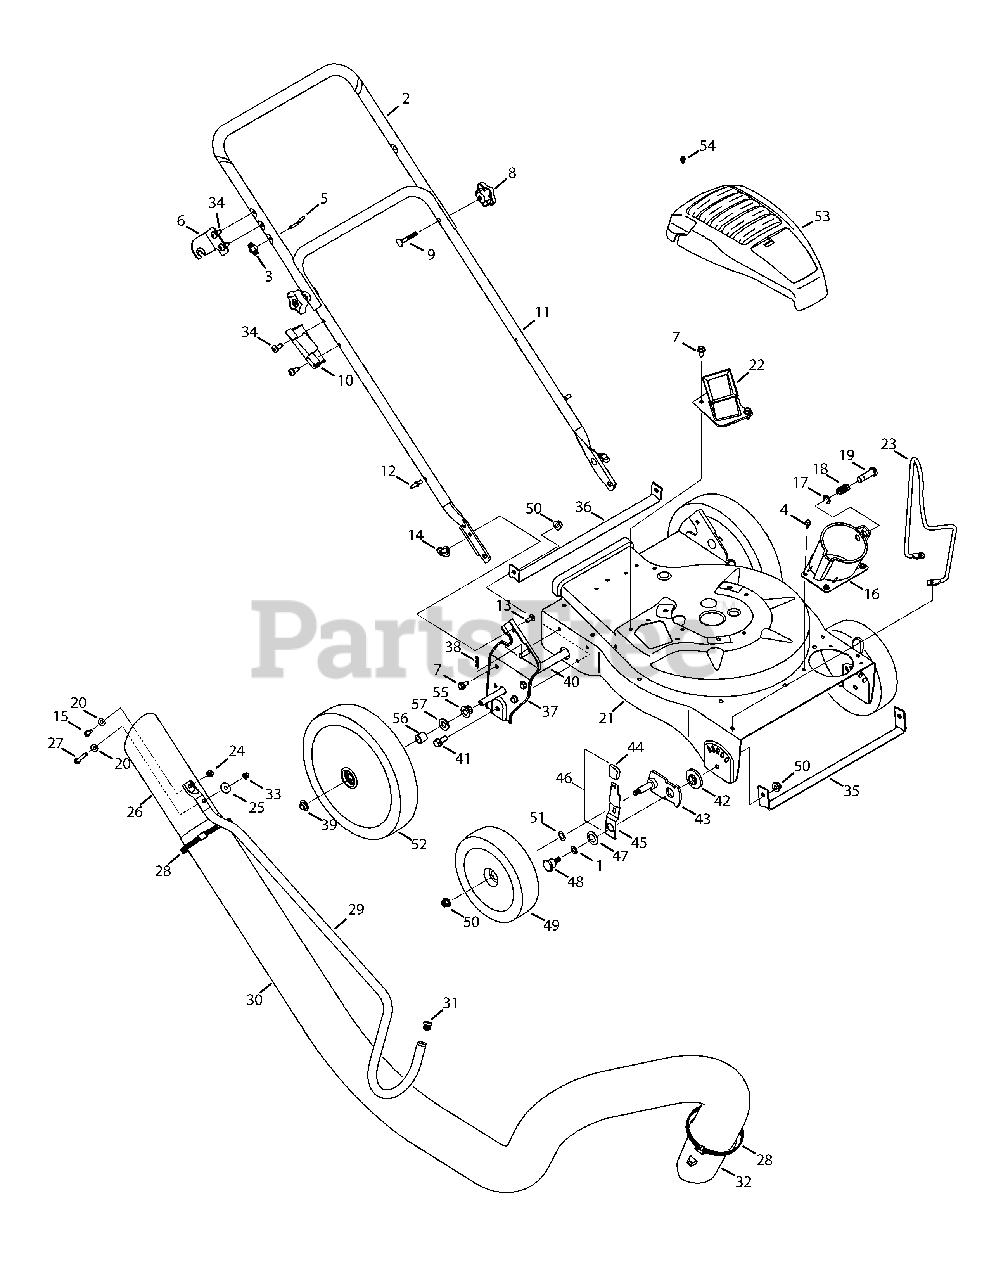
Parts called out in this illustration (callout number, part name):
1	Thrust Washer.375 ID x.70 OD
4	Screw, 1/4-20 x .500
6	Upper Handle Bracket
7	Hex Cap Screw 5/16-12 x.750
9	Carriage Bolt
10	Nozzle Handle Clip
13	Carriage Screw 1/4-20 x.75
14	Wing Nut 1/4-20
15	Hex Cap Screw 1/4-20 x.620
16	Hose Base Adapter Assembly (Incl. Ref.# 17-19)
17	E Ring.500 Dia
18	Compression Spring
19	Clevis Pin
20	Flat Washer.271 ID x.630 OD
21	Upper Flail Housing
22	Chipper Chute Assembly
23	Hose Cradle
24	Flange Lock Nut, 1/4-20
26	Hose Nozzle
27	Hex Cap Screw 1/4-20 x 2.625
28	Adjustment Clamp
30	Vacuum Hose
31	Handle Plug
32	Hose Adapter
33	Cap Lock Nut, 1/4-20
34	TT Screw, 5/16-18 x .750
35	Front Wheel Support Brace
36	Rear Wheel Support Brace
37	Handle Bracket Ass’y RH
37	Handle Brkt Ass’y LH
38	Cotter Pin
41	HHflg, 3/8-16 x .875
42	Height Adjustment Bearing
43	Pivot Arm Assembly
44	Height Adjustment Knob
45	Spring Lever
46	Height Lever Assembly (Incl. Ref.# 44-45)
47	Bell Washer.760 ID x.25 OD
48	Shoulder Screw,.750 x.500
49	Front Wheel
50	Flange Lock Nut, 3/8-16
51	Washer, Wave, .531 x .781 x .013
52	Rear Wheel
53	Engine Shroud
54	Screw, #10-16 x 1.25
55	Brg. Flg, Hex
57	Washer, Flat, .508ID x 1.00 OD
